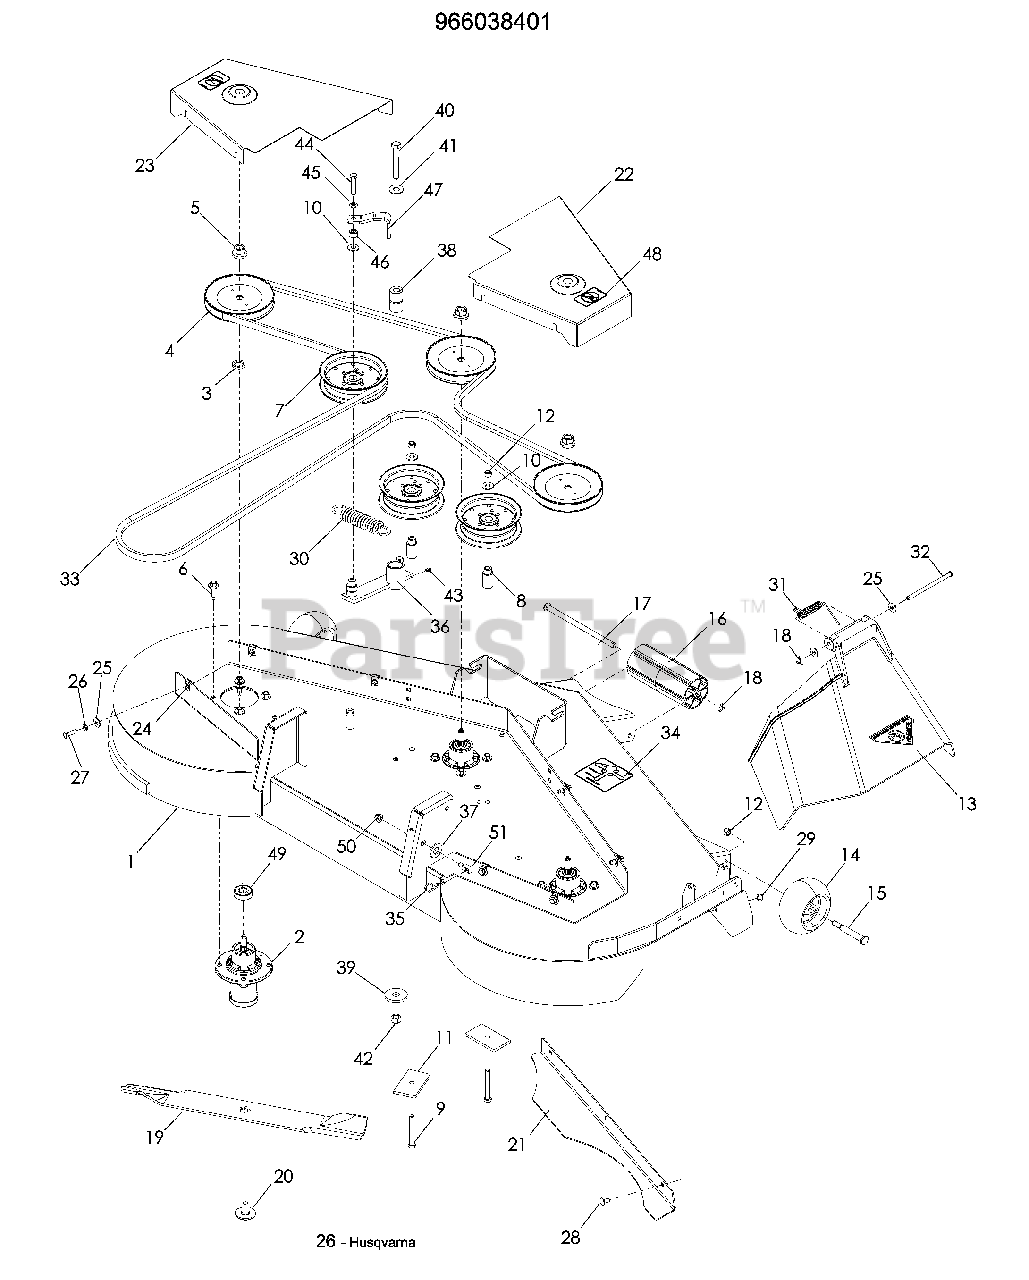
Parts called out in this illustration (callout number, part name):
1	DECK w/DECALS 61"
3	WASHER-SPACER
5	NUT 9/16 TOP CNTRLK
6	SCREW, WASHER HEAD
7	PULLEY, IDLER
8	BUSHING, IDLER
9	HCS 3/8-16 x 3
10	WASHER 3/8
11	PAD
12	NUT 3/8-16 NYLOC
13	CHUTE, DISCHARGE
14	WHEEL, GAUGE
15	BOLT, SHOULDER
16	ROLLER, NOSE
17	ROD, NARROW
18	PIN, COTTER 1/8 x ¾
19	BLADE, 21"
20	BOLT 7/16 BLADE
21	CONFINEMENT PLATE
22	BELT SHIELD RT
23	BELT SHIELD LT
24	RETAINER 5/16-18
25	WASHER 5/16
26	LOCKWASHER 5/16
27	HCS 5/16-18 x 1
28	RHSNB 5/16-18 x 5/8
29	NUT 5/16-18 NYLOC
31	SPRING, TORSION
32	PIN, CLEVIS 5/16
33	BELT, DECK
34	DECAL, BELT ROUTING
35	HAIRPIN #4
36	ARM, IDLER
37	WASHER 5/8 FLAT SAE
38	BUSHING, PIVOT
39	WASHER, SUPPORT
40	HCS ½-13 x 3¼
42	NUT ½ NYLOC
43	ZERK
44	HCS 3/8-16 x 1¾
45	WASHER 3/8 SLW
47	GUIDE, BELT
48	DECAL, NO STEP
49	BEARING, BALL
50	NUT 5/16-18, FLANGE NYLOC
51	STUD, w/ANTI- ROTATE
